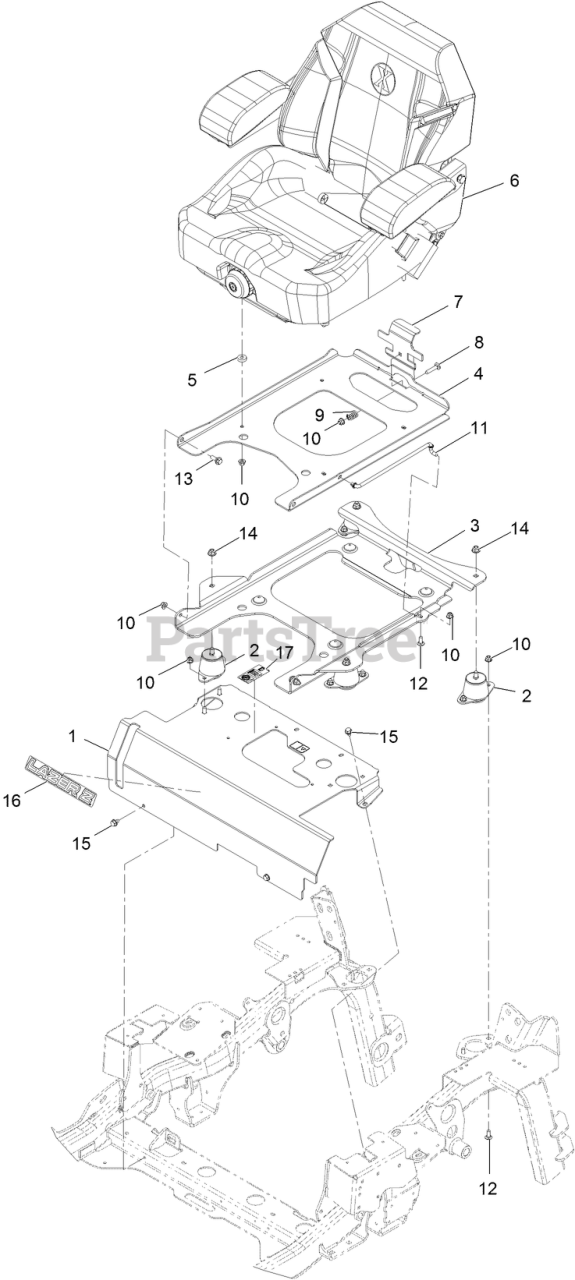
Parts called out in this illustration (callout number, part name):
1	SEAT MOUNT ASM
2	ISOLATOR-SEAT
3	PLATE-SUPPORT, TILT SEAT
4	PLATE-FRAME, SEAT
6	KIT-SUSPENSION SEAT
7	PLATE, SEAT LATCH
8	BOLT-CARR
9	SPRING-COMPRESSION
10	NUT-HF, NI
11	ROD-PROP
12	SCREW-CARR
13	SCREW-SHOULDER
14	NUT-HF, NI
16	DECAL, LAZER MODEL
17	DECAL-TRANS FLUID
